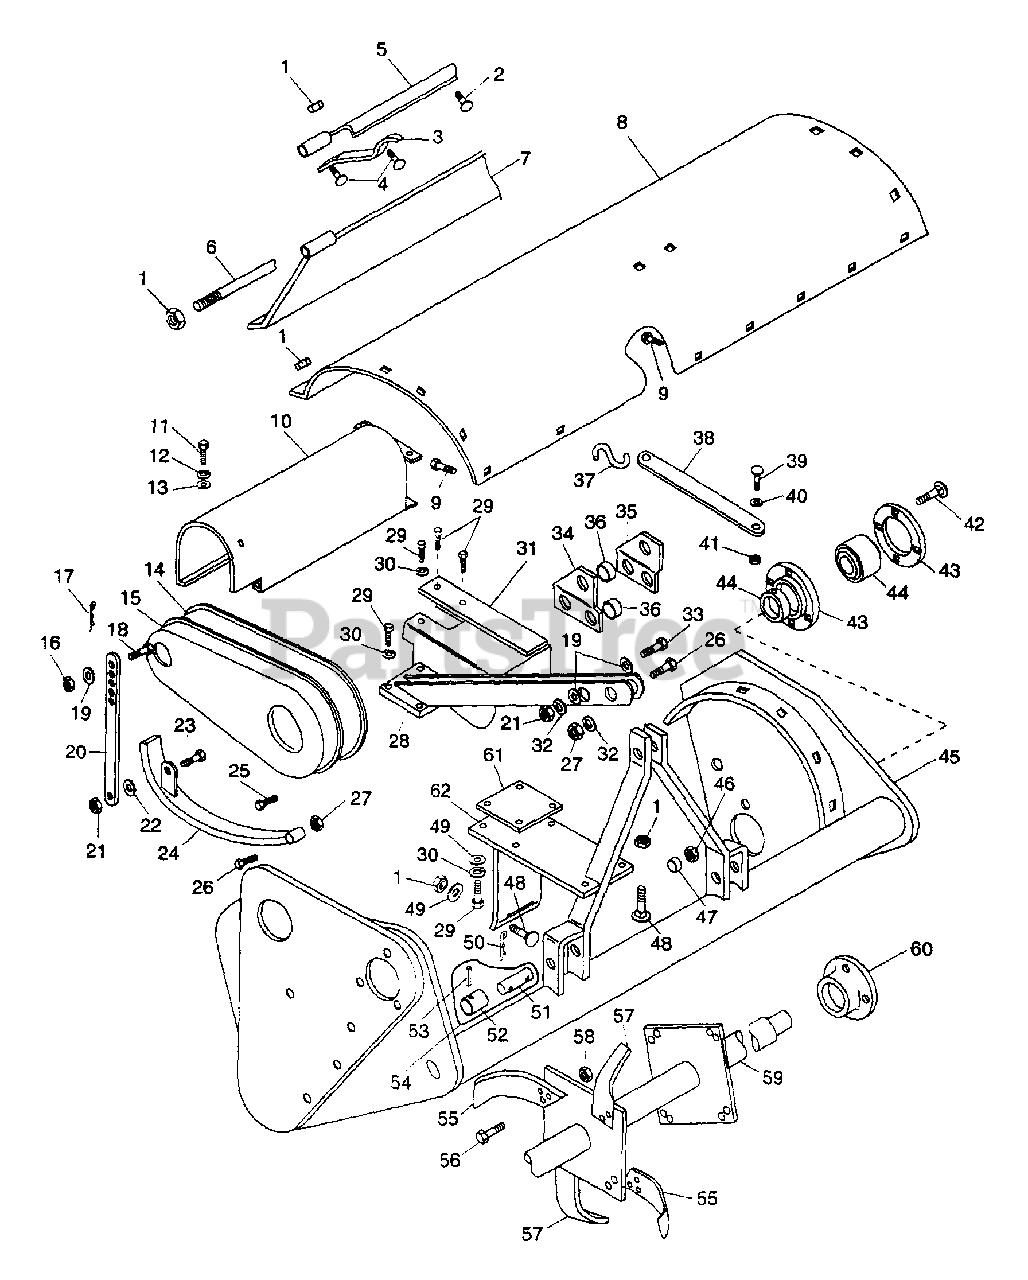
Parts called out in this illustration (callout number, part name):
1	NUT-LK TOP .375-16 GR C YWZC
2	BLT-RDHDSQNK .375-16X.75 GR5PL
4	BLT-RDHDSQNK .38-16X1.25 GR5PL
5	HINGE BRACKET
6	ROD-HINGE
7	LEVEL BLADE
8	SHROUD W/DECALS
9	SCR-TAP .312-18X.75 HWHPLDFGT
10	TUNNEL SHIELD
11	BLT-HEX .31-18X.50 PL GR2
12	WSHR-LK .313X.078 PL MED
13	WSHR-FL-STL.312X.734X.065PL
15	OUTER SHIELD
16	NUT-HEX .625-11
17	PIN-HAIR EXT .12X.31X2.37 PL
18	HEX BOLT-.62-11 X 1.50 SPECIAL
19	WSHR-FL-STL .505X1.000X.062
20	ADJUST STRAP
21	NUT-LK-CROWN .50-13 GR C PL
22	RUBBER WASHER
23	BLT-HEX .50-13X1.50 PL GR2
25	SCR-TAP .312-18X.50 HWH PL 1A
26	BLT-HEX .62-11X2.50 PL GR5
27	NUT-HEX .625-11
28	UPPER LINK
29	BLT-HEX .38-16X1.25 PL GR5
30	WSHR-LK .375X.115 HVY PL
31	PTO SHIELD
32	WSHR-LK .563X.141 MED PL
33	BLT-HEX .50-13X3.25 GR5
34	BRACKET RH
35	BRACKET LH
36	SPACER .630X.875X.625
38	RUBBER STRAP
39	SCR-MCH .25-20X1.25 SLRH PL
40	WSHR-FL-STL .250X.562X.049 PL
41	NUT-HEX .250-20 PL
42	BLT-RDHDSQNK .50-13X1.75 PL
43	FLANGETTE-4 HOLE
44	BRG-BALL 1.50X80MMX1.7
46	NUT .50-13 PL
47	SPACER .510X.750X.312
48	BLT-RDHDSQNK .38-16X1.0 GR5PL
49	WSHR-FL-STL .38X.875X.083 PL
50	PIN-HAIR INT .14X.4X2.75
52	SPACER .635X.875X1.370
53	PIN-ROLL .250X3.00
54	PIN ASSEMBLY
55	TINE RH
56	BLT-HEX .38-16X1.13 GR9
57	TINE LH
58	NUT-LK-FLG .375-16 PL
59	TINE SHAFT
60	CAP-BEARING GUARD
61	SPACER PLATE
62	GEAR BOX MOUNT
